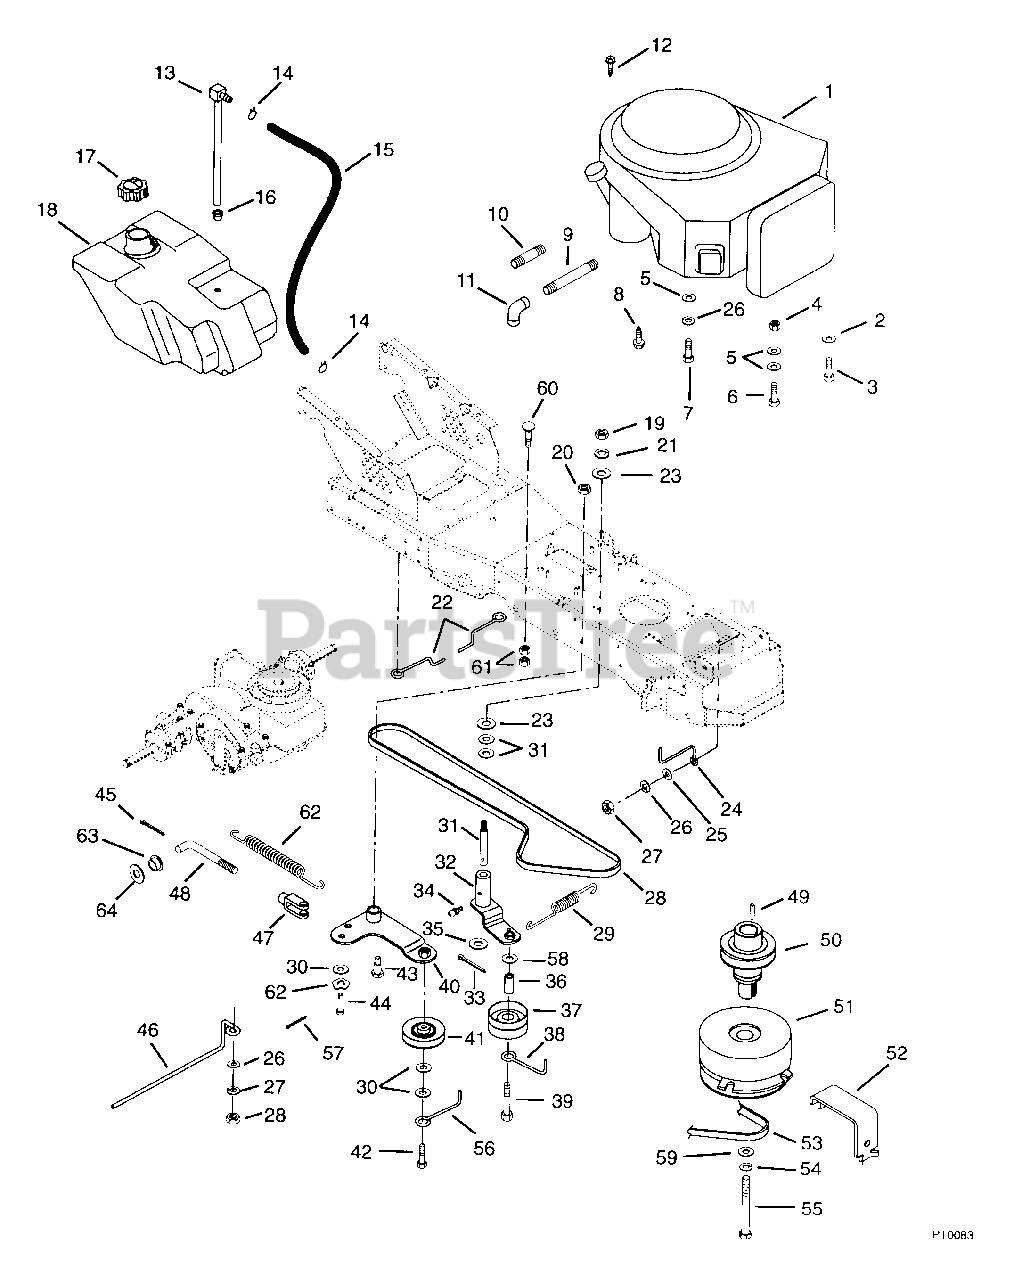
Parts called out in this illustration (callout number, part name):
1	ENGINE- 16.0 B&S VANGUARD TWIN
1	ENGINE- 13.0 TEC OHV ENDURO
1	ENGINE- 16.0 TEC OHV
1	ENGINE- 14.0 B&S VANGUARD SING
1	ENGINE- 16.0 B&S VANGUARD SING
1	ENG- 15.0 KOHLER OHV PS-41531
2	WSHR-LK-EXT .375X.050
3	SCR-TAP .375-16X1.25 HWH PL TR
4	NUT-LK-TOP .312-18 GR C PL
5	WSHR-FL-STL .328X.875X.062 PL
6	BLT-HEX .31-18X1.50 PL GR5
7	BLT-HEX M8 X 1.25X25 PL GR5
8	SCR-TAP .375-16X1.0 HWH PL TR
9	NIPPLE
10	NIPPLE
11	ELBOW .375-18 NPTF
12	SCR-TAP .312-18X.75 HWH PL TR
13	TANK FITTING
14	CLAMP-HOSE WIR.490/.510X.092#8
15	HOSE- FUEL LINE 36.00"
15	HOSE- FUEL LINE 48.00"
15	HOSE- FUEL LINE 50.00"
16	BSHG-FLG .375 X 1.062 X .625 R
17	FUEL CAP
18	FUEL TANK
19	NUT-HEX .375-16
20	NUT-LK-CTR .375-16 GR A PL
21	WSHR-LK .375X.094 MED PL
22	BELT FINGER
23	WSHR-FL-STL .438X1.0X.083 PL
24	BELT FINGER
25	WSHR-FL-STL.312X.734X.065PL
26	WSHR-LK .313X.078 PL MED
27	NUT-JAM .312-18 PL
28	V-BELT, 4L-WRAPPED
29	SPRING, EXT
30	WSHR-FL-STL .390X.750X.125 PL
31	SHOULDER STUD
32	ARM - IDLER PIVOT
33	PIN-COTR .18X1.25 PL
34	FTG-LUBE .25-28X.256 YWZC
35	WSHR-FL-STL .520X.827X.062 YZ
36	TUBE .380 X .625 X 1.620
37	IDLER-FLAT 3.25 X .38 NWHAMSHR
38	FINGER - BELT
39	BLT-HEX .38-16X3.50 PL GR5
39	BLT-HEX .38-16X3.75 PL GR5
40	IDLER PIVOT ARM
41	IDLER-V 3X.38
42	BLT-HEX .38-16X1.75 PL GR2
43	BLT-SHLDR .38-16X1.25
44	PIN-CLEV .312X.822 HDND PL
45	PIN-COTR .09X.75 PL
46	FINGER - BELT
47	YOKE, .312-24 X 2.25
49	KEY-SQ .25 X 1.25 X .25 SAE
50	SHEAVE EXTENSION SHAFT-GEAR
50	SHEAVE EXTENSION SHAFT- HYDRO
51	ELECTRIC CLUTCH/BRAKE (3.4AMP)
51	ELECTRIC CLUTCH/BRAKE(1.8AMP)
51	CLUTCH, ELECTRIC - WARNER
52	ANCHOR - CLUTCH
53	V-BELT, 4L-RAW EDGE
54	WSHR-LK .438X.133 HVY
55	SCR-CAP .44-20X4.00 GR5 HHPL
55	BLT-HEX .44-20X4.50 GR8 YWZC
56	FINGER - BELT
57	PIN-HAIR INT .08X.18X1.18
58	WSHR-FL-STL .390X.875X.18 PL
59	WSHR-FL-STL .463X1.375X.250 PL
60	BLT-RDHDSQNK .31-18X1.0 SHT PL
61	NUT-LK .312-18 GR A PL
62	SG-TENS .105X.85X5.00 WLD 40
63	BSHG-FLG .320X.620X.312 NY
64	WSHR-FL-STL .505X.880X.072 YWZ
65	WAVE WASHER .531X.781X.125FH
